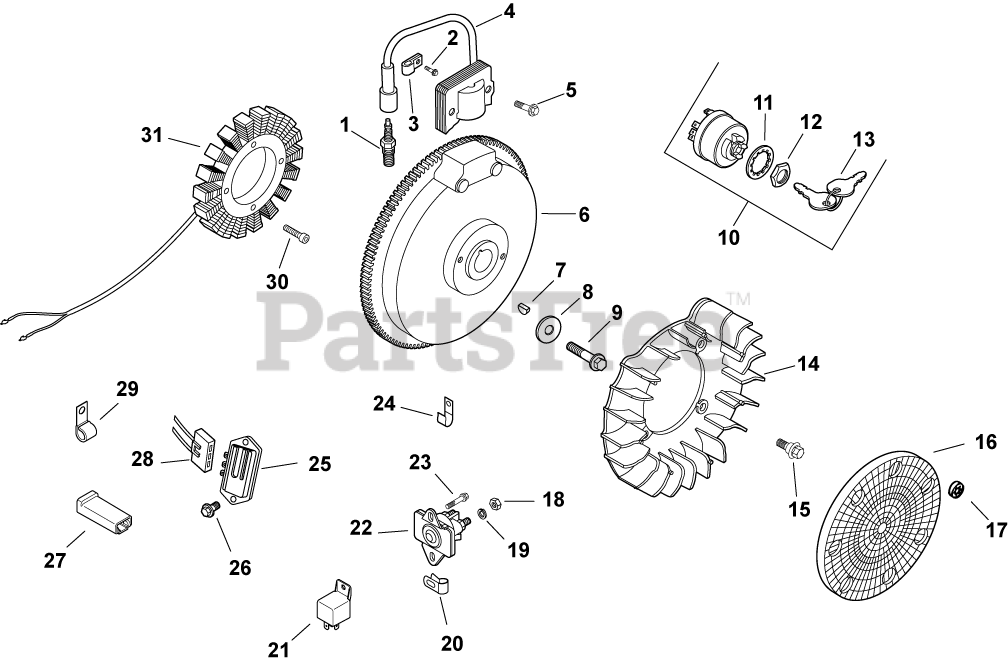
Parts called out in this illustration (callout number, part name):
1	PLUG, SPARK (PRO SERIES)
2	SCREW, FLG THD FRM M5X.8X10
4	MODULE, IGNITION
5	SCREW, FLG THD FRM M5X.8X20-(#25086399S)
7	KEY, 3/16" X 5/8"
8	WASHER, FLAT 13/32"
9	SCREW, FLG M10X1.5X45 - (#25086361S)
10	SWITCH ASSY, KEY (KM)-USE 25 099 32-S
11	WASHER, INTERNAL TOOTH
12	NUT, KEY SWITCH
13	KEY, SET -USE 48 340 01-S
15	BOLT, SHOULDER
16	SCREEN, GRASS
18	NUT, JAM 1/4-20 GRADE 2
19	WASHER, INT TOOTH LOCK 1/4"
20	CLIP, TUBE & WIRING (KM)
22	SOLENOID - WATERPROOF (KM)-USE 25 435 08
23	SCREW,FLG THD FRM M6X1.0X16-(#25086397S)
24	CLIP, CABLE
25	REG/RECT-15 AMP (KM)-USE 41 403 10-S
26	SCREW, FLG M6X1.0X16
27	CONNECTOR (1 CONTACT)
28	CONNECTOR, BODY (KM)-USE 25 155 41-S
30	SCREW, M5X0.8X25 - (#25086402S)
31	KIT, 15 / 20 AMP STATOR
